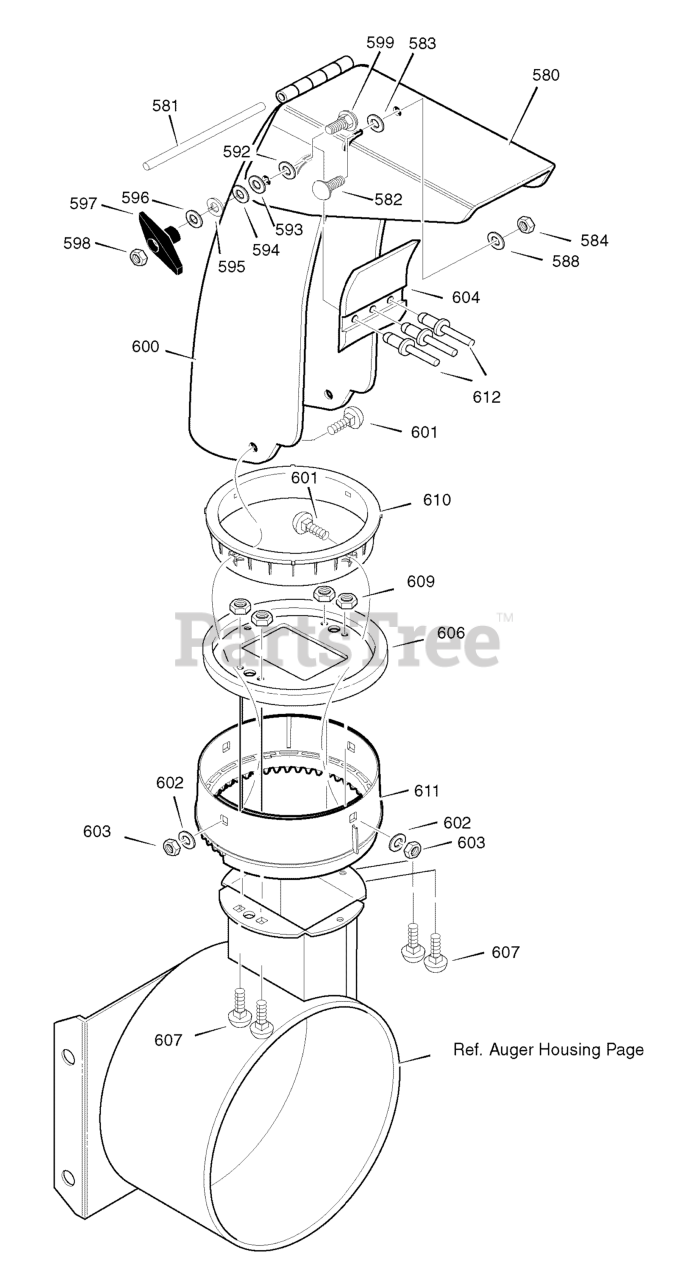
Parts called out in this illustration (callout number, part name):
580	CHUTE, UPPER HALF
581	PIN, HINGE
582	BOLT, CARRIAGE 5/16-18 X.75
583	WASHER, PLASTIC
584	NUT, 5/16-18 REGHEX NYLOCK
588	WASHER, PLASTIC
592	WASHER, PLASTIC
593	WASHER, PLASTIC
594	WASHER, FLAT
595	WASHER, SPLIT
596	WASHER, FLAT
597	KNOB, T 3.00
598	NUT, 5/16-18 REGHEX
599	BOLT, 5/16-18X1.00
600	CHUTE, LOWER HALF
601	BOLT, 5/16-18 X1.00
602	WASHER, FLAT
603	NUT, 5/16-18 HEXNYL
604	FLAP, CHUTE
606	CHUTE COLLAR
607	SCREW, 1/4-20 X 0.75
609	NUT, 1/4-20 HEX NYLOCK
610	RETAINER RING INNER
611	RETAINER RING OUTER
